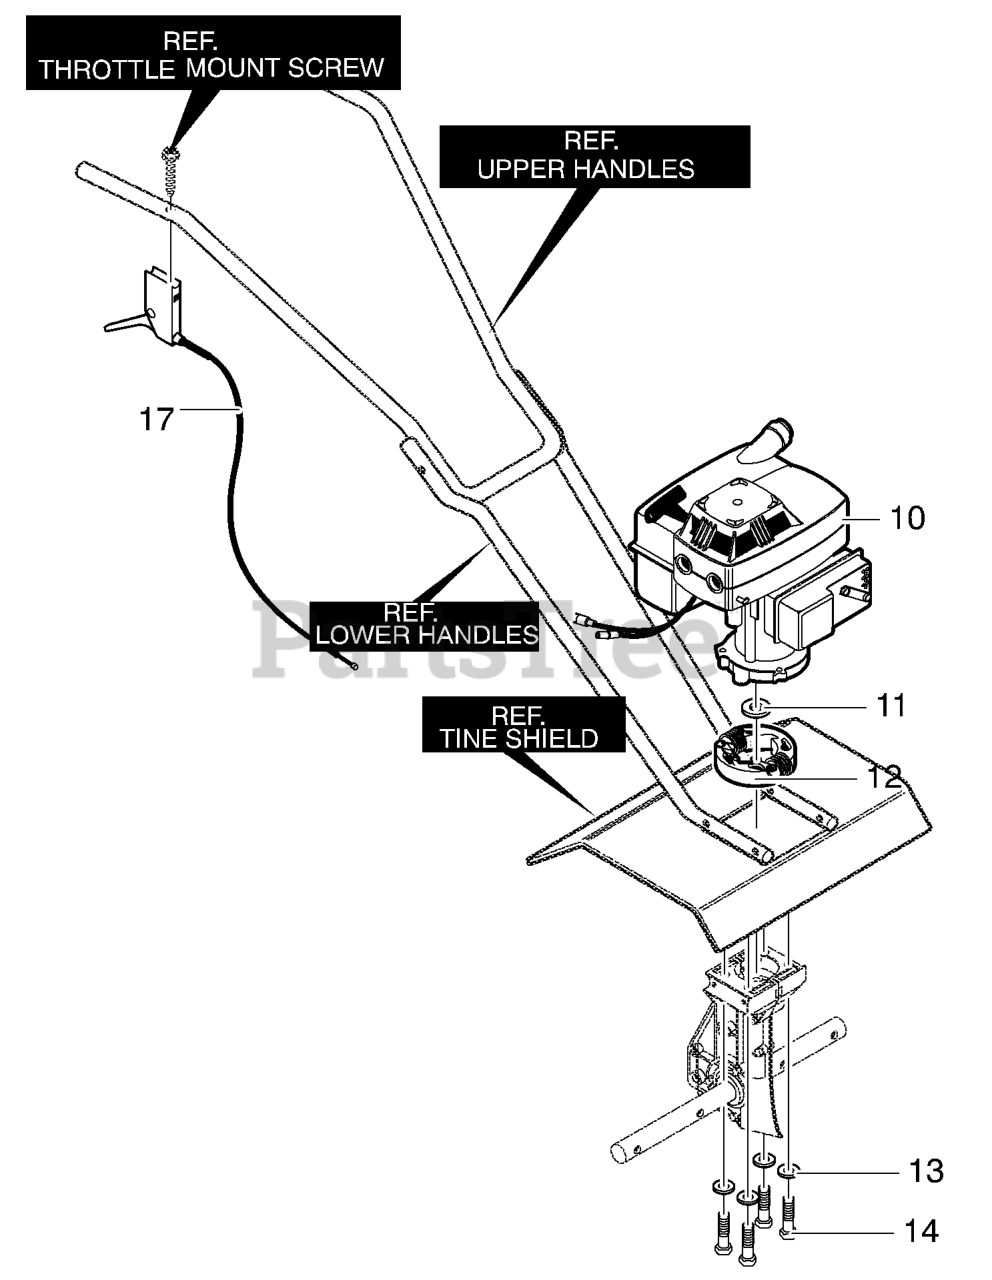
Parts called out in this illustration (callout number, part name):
10	Engine
11	Flat washer
13	Washer, Regsptlk
14	Bolt
17	Cable, Throttle
